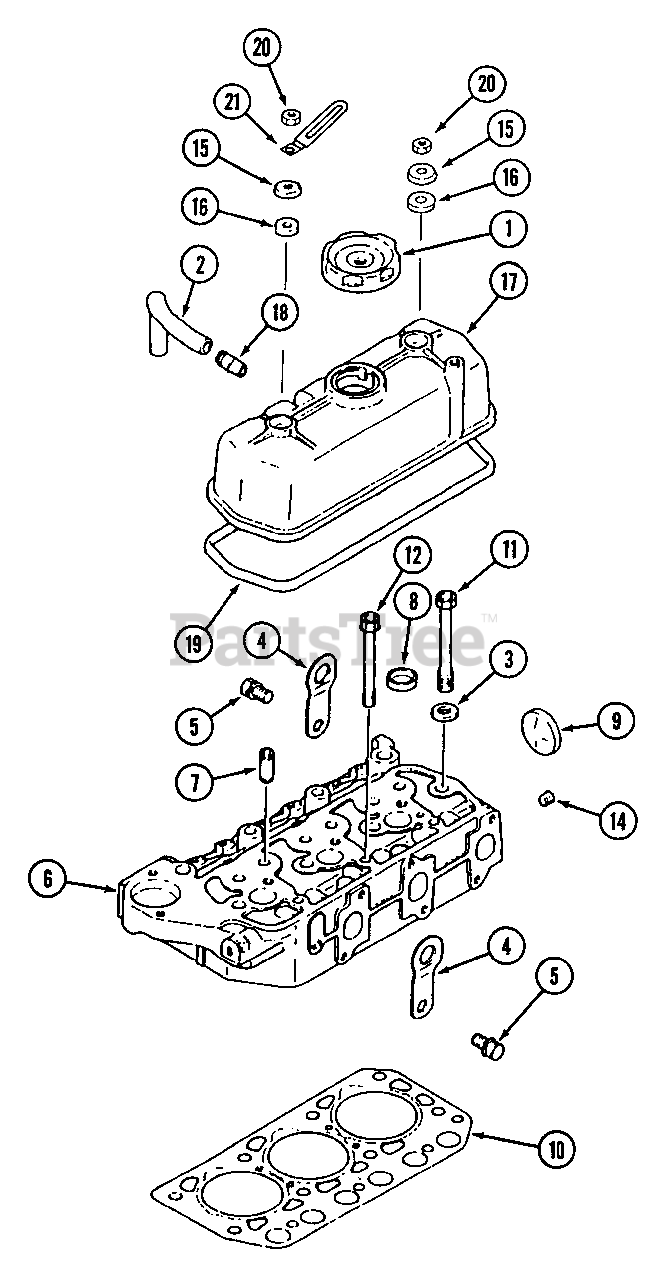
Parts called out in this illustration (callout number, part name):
1	Cap, Oil Filter
2	Pipe, Air Breather
4	Hanger, Engine
5	Bolt,
6	Cylinder, Head Ass'y.
7	Guide, Valve
8	Cap, Sealing
9	Cap, Sealing
10	Gasket, Cylinder Head
11	Bolt, Cylinder Head
12	Bolt, Cylinder Head
14	Plug, Taper
17	Rocker, Cover
18	Pipe
19	Gasket, Rocker Cover
